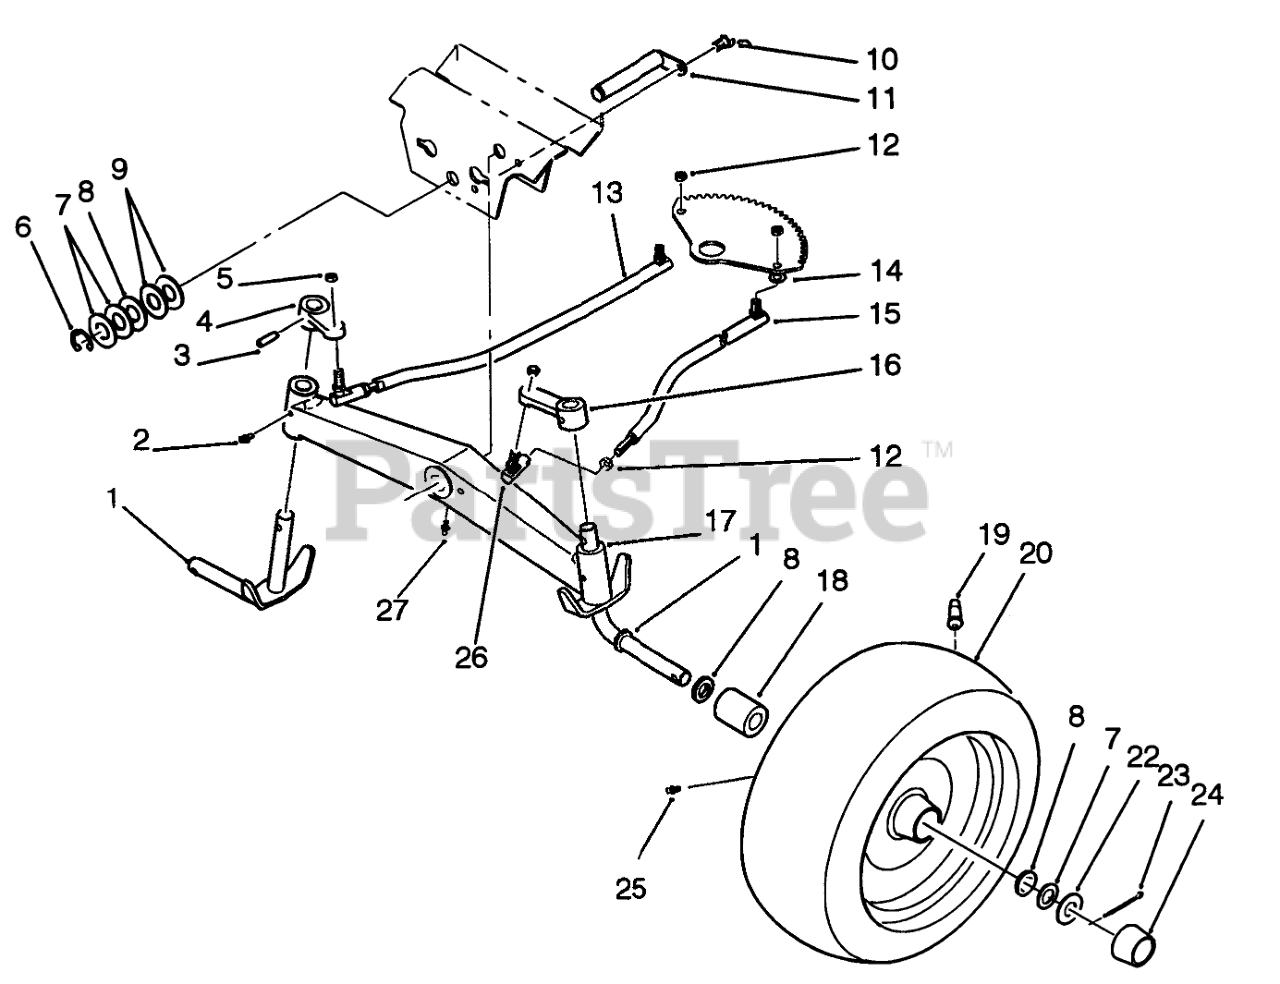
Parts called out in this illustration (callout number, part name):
1	Spindle
2	FITTING-GREASE
4	Arm-Spindle, R.H.
5	Nut
6	E-RING
7	WASHER-SHIM
8	WASHER
9	WASHER
10	Bolt
11	WLDMT-AXLE PIN R
12	NUT-6
13	Ball Joint
14	Collar
15	Steering Link Rod, L.H.
16	Arm-Spindle, L.H.
17	Axle-Front
18	BEARING-WHEEL
19	VALVE
20	Tire (16 x 6.5-8) 2-Ply -2 Wheel Axel
22	WASHER WHEEL
23	PIN-COTTER
24	HUBCAP
25	ZERK-GREASE
26	ASM-Rod
27	FITTING-GREASE
